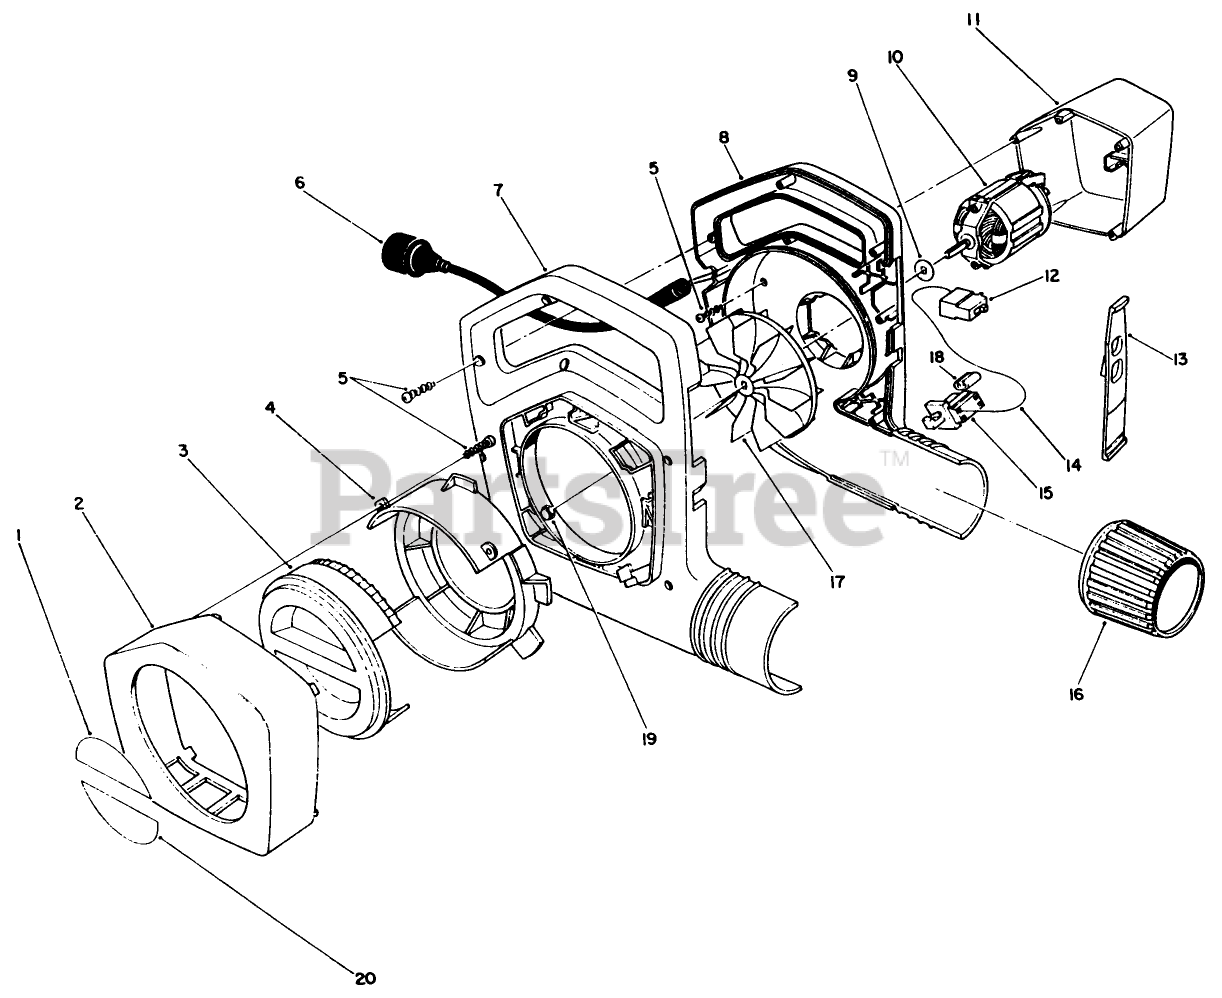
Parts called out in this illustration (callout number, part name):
1	UPPER CHOKE DECAL-CLUB
2	BV-TRIM RING WH RED
3	BV CH ADJUSTER WH RED
4	Ring-Tab
5	Screw
6	POWER SUPPLY CORD,9.5"
7	Housing-Blower, R.H.
8	Housing-L.H.
9	Washer-Impeller
10	MOTOR, BLOWER (450/550)
11	Cover-Motor
12	Switch-On/Off
13	Cam-Switch-On/Off
14	WIRE -INTERNAL
15	SWITCH-INTERLOCK
16	Collar-Output
17	IMPELLER-NEW STYLE
18	NEW STYLE DUST PLUG
19	NUT-LOCK, CAP
20	LOWER CHOKE DECAL-CLUB
